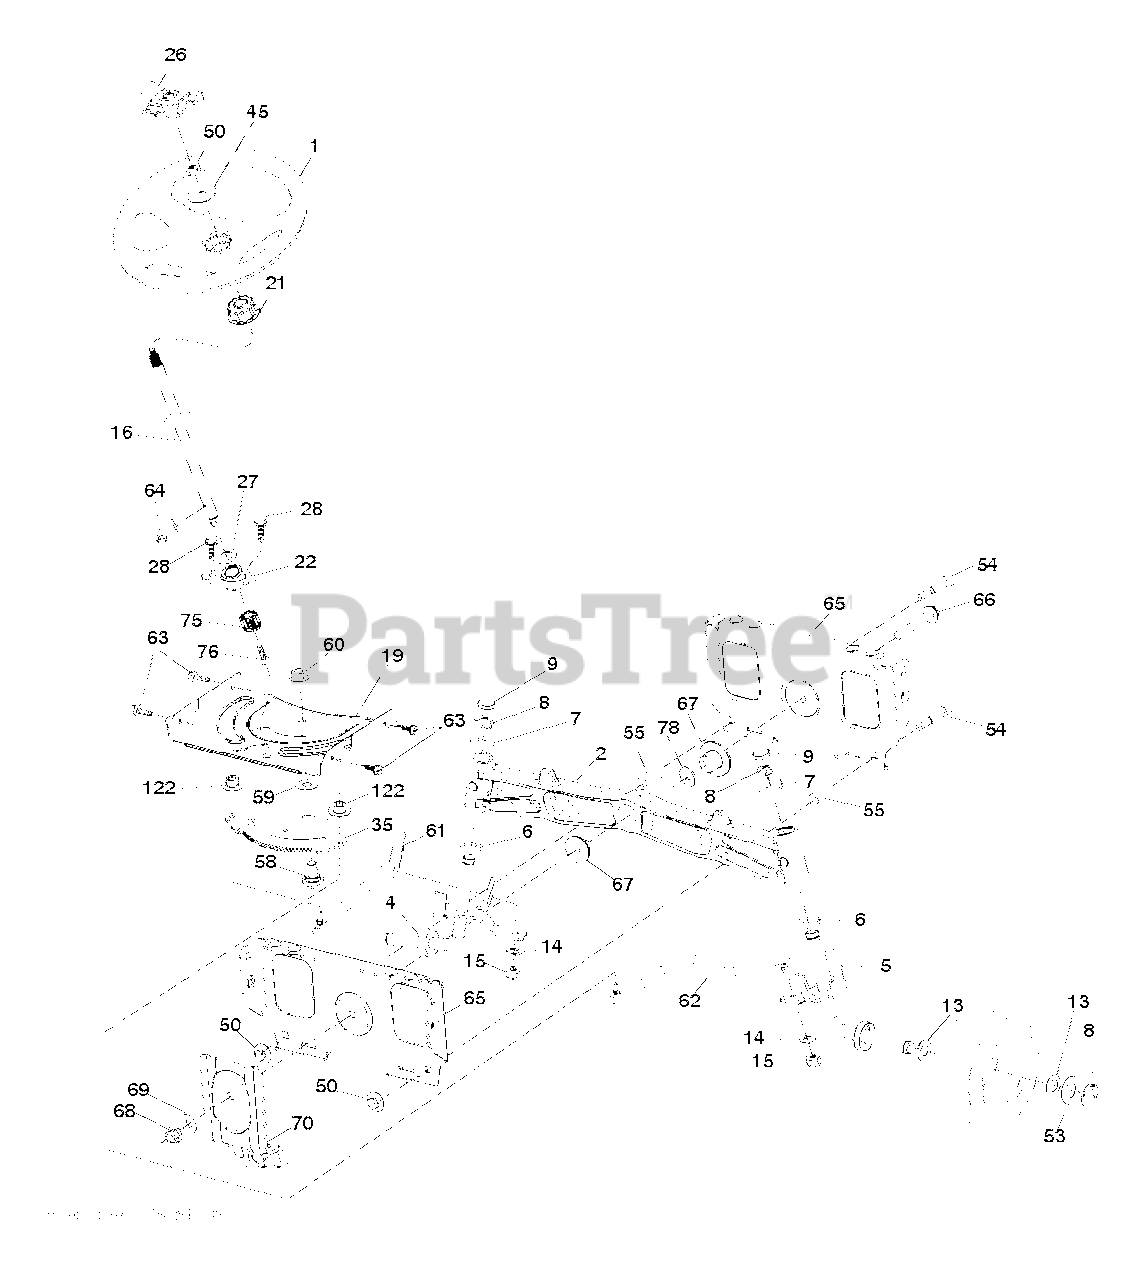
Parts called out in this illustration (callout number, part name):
1	WHEEL.STEER.HUSQ.SR.498.OVMLD
2	AXLE.CAST.IRON
4	SPINDLE.WELDED.LH.16"TEX
5	SPINDLE.WELDED.RH.16"TEX
6	THRUST WASHER
9	CAP.SPINDLE.BLACK
14	WASHER, LOCK 3/8
15	NUT CROWNLOCK 3/8-24
16	SHAFT.STEER.2HIGH.SPLND.PLATED
19	PLATE.STEER.DDL.NLT/NG
21	ADAPTER.WHEEL.STEER.SPLND.ALUM
22	BEARING.SHAFT.STEER.LOWER.625
26	INSERT.CAP.WHL.STRG.HUSQ.PREM
28	SCREW, 3/8-16X3/4
35	GEAR.SECTOR.PLATE.DDL.
45	WASHER.3/8ID.2-3/8OD.12GA.PLTD
50	NUT LOCK FLG 3/8-16 UNC
53	WASHER.HARDENED
55	SPACER.BRACE.AXLE
58	BOLT.SHOULDER.SECTOR.P
59	WASHER.THURST.SECTOR.S
60	NUT FLANGE LOCK 5/8-11
61	DRAGLINK.LH.BALLSTUD.D
62	DRAGLINK.RH.BALLSTUD.D
63	SCREW
64	RETAINER.CLIP.SPRING.S
65	BRACE.AXLE.FRONT.NLT/N
66	BOLT HEX FGHD 7/16-14 X 3 SERR
67	BUSHING.PM.FRONT AXLE
68	NUT.LOCK.FLANGE.7/16
69	WASHER.1.5X.505X.118
70	BRACKET.FRT.DECK.SUSP.RR.MT431
75	PINION.ZINC PLATED
76	SCREW HEAD SOCKET LRVB
78	THRUST WASHER
122	CAP.GEAR.SECTOR.TEX
